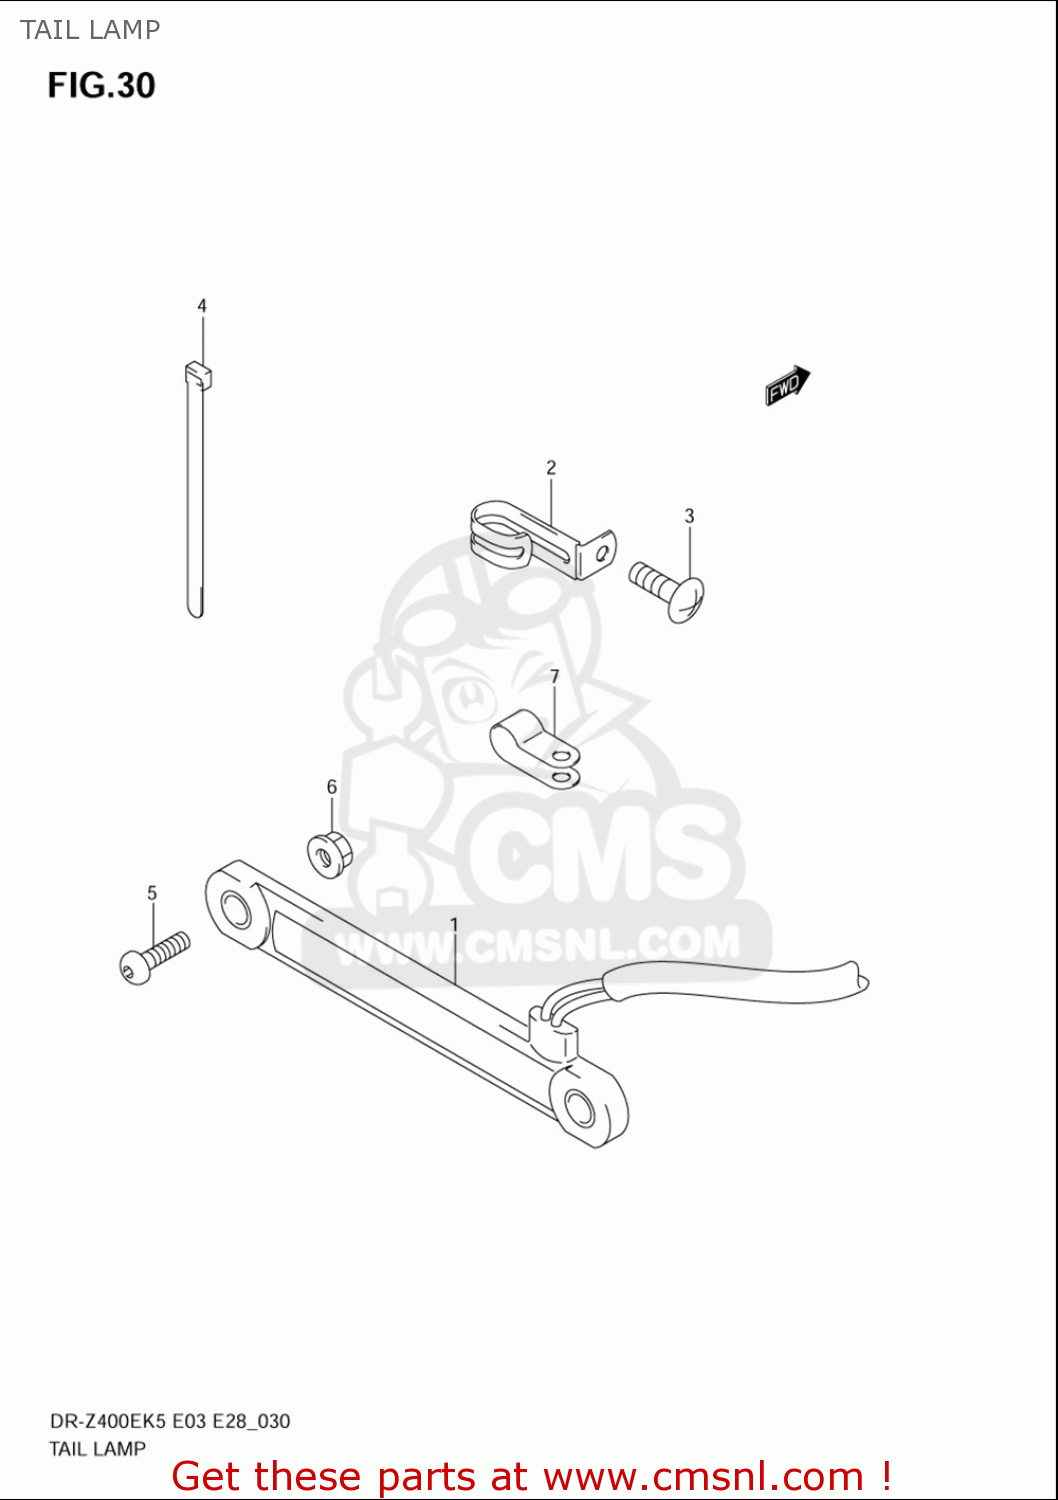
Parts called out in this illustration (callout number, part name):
1	LAMP ASSY,TAIL
2	CLAMP,TAIL LAMP LEAD
3	SCREW(5X18)
4	CLAMP(L:100)
5	SCREW
6	NUT
7	CLAMP
